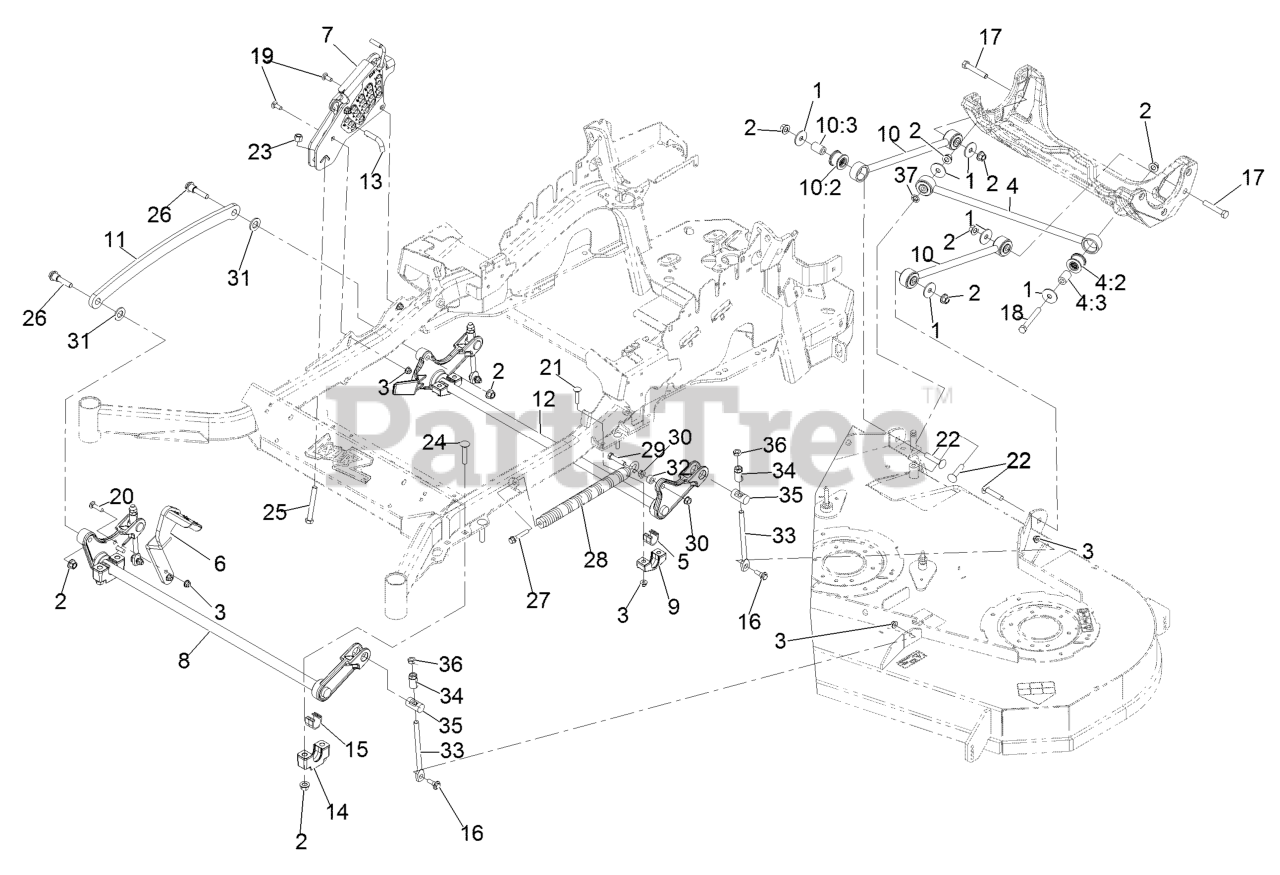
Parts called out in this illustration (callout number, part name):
1	WASHER-THRUST
2	Nut-Lock 1/2-13
3	NUT-HF, NI
4	PANHARD ROD ASM
4:2	BUSHING-SUSPENSION, RUBBER
5	BEARING-CROSS SHAFT, REAR
6	LEVER-FOOT
7	HOC ASM
8	DECKLIFT-FRONT
10	DECK STRUT ASM
10:2	BUSHING-SUSPENSION, RUBBER
11	LINK-LIFT, DECK
12	LIFT-DECK, REAR
13	PIN-HOC
14	SUPPORT-CROSS SHAFT, BEARING
15	BEARING-CROSS SHAFT, FRON
16	SCREW-SHOULDER, HHF
17	SCREW-HH
18	SCREW-HH
19	BOLT-CARR
20	SCREW-CARR
21	SCREW-CARR
22	SCREW-CARR
23	NUT-LOCK, NI
24	Bolt-Carriage 1/2-13 X 2 1/2 Spl Neck
25	BOLT-TAP
26	SCREW-HHF, SHOULDER
27	BOLT-SHOULDER
28	SPRING-EXTENSION
29	SCREW-HH
31	WASHER-FLAT
33	LINK-ADJUSTER, DECK LIFT
34	ADJUSTER-LIFT, DECK
35	TRUNNION
36	NUT-JAM
37	NUT-PUSH
